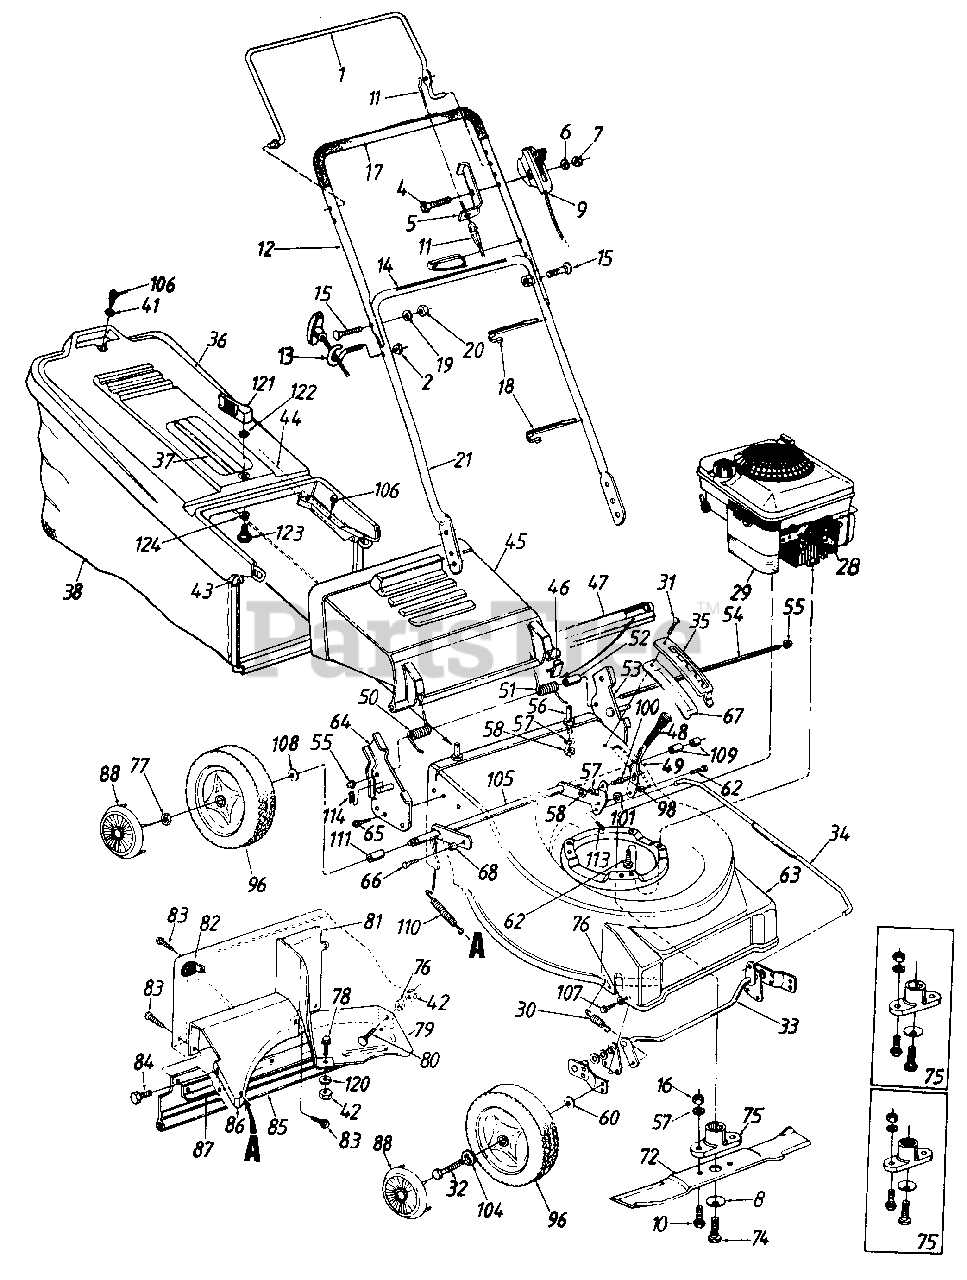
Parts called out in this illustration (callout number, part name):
1	Control Handle
2	Hex L-Nut 1/4-20 Thd.
4	Hex Bolt 1/4-20 x 1.875" Lg.*
5	Cable Brkt.
6	Spr. Wash. '/4" I.D.
7	Hex Nut 1/4-20 Thd.
8	Bell-Wash. .39" I.D.
9	Throttle Control Ass'y. Comp.- 43.62"
10	Hex Bolt 3/8-24 x 1" Lg.
11	Control Cable-55"
15	Curved Carriage Bolt 5/16-18 x 1.38" Lg.
16	Hex Nut 3/8-24 Thd.
17	Foam Grip
18	Cable Tie
19	L-Wash. 5/16" I.D.
20	Hex Nut 5/16-18 Thd.*
21	Lower Handle
28	Spark Plug Boot
29	Engine
30	Extension Spring 2.39" Lg.
31	Torx Hd. AB-Tap Scr. 1/4"-.62" Lg.
32	Axle Bolt
34	Height Adj. Connecting Rod
35	Height Adjustment Plate
36	Hardtop Bag Cover
37	Hardtop Handle
38	Grass Bag
41	Fl-Wash. .281" I.D. x .62" O.D.
42	Hex Nut 1/4-20 Thd.
44	Rear Catcher Frame
45	Chute Deflector
46	Deflector Plug
47	Seal-Extrusion
49	Spring Lever
50	Torsion Spring-R.H.
51	Torsion Spring-L.H.
52	Spacer.255" I.D.
53	Handle Brkt. Ass'y.-L.H.
54	Hinge Pin 17.75" Lg.
55	Cap Speed Nut
56	Shld. Pin 3/8-24 x 1.43" Lg.
57	L-Wash. 3/8" I.D.*
58	Hex Jam Nut 3/8-24 Thd.
60	Bell-Wash. .38" I.D. x .88" O.D.
62	Hex L-Wash. Hd. Scr. 3/8-16x 1" Lg.
63	21" Deck Ass'y.
64	Handle Brkt. Ass'y.-R.H.
65	Hex L-Wash. Hd. AB-Tap Scr. 1/4 x.62" Lg.
66	Hex Wash. Hd. Tap Scr. 3/8-16 x .75" Lg.
67	Height Adjustment Support
68	Spacer.385" I.D.
72	21" Blade
74	Hex Bolt 3/8-24 x 1.5" Lg.
75	Blade Adapter Kit (Keyed)
76	L-Wash. 1/41" I.D.*
77	Hex Jam Nut 1/2-20 Thd.
78	Hex Bolt 1/4-20 x .85" Lg.
79	Rear Belt Baffle
80	Carr. Bolt 1/4-20 x .50" Lg.*
83	Torx Mach. AB-Tap Scr. 1/4 x .62" Lg.
84	Hex B-Tap Scr. 1/4 x .38" Lg.
85	Rear Flap
96	Wheel Ass'y. Comp.
98	Shld. Spacer .50" Dia.
100	Shld. Pin 3/8-24 x 1.43" Lg.
101	Fl-Wash. .375" I.D. x 1.0"
104	Wave Wash. .53" I.D. x .78"
105	Rear Axle Ass'y.
106	Hex L-Wash. AB-Tap Scr. 1/4 x .62" Lg.
107	Hex L-Wash. HD AB-Tap Scr. 1/4 x .38" Lg.
108	Fl-Wash. .510" I.D. x .75"
109	Spacer. 526" I.D.
110	Extension Spring 3.8" Lg.
111	Sleeve.526" I.D.
113	Cotter Pin 3/32" Dia. x .75"*
114	Internal Cotter Pin 5/16" Dia.
120	Bell-Wash. 1/4" I.D.
121	Grass Catcher Locking Knob
122	Internal L-Wash. 1/4" I.D.
123	Shld. Bolt .342" Dia. x .268
124	Wave Washer 3/8" I.D.
